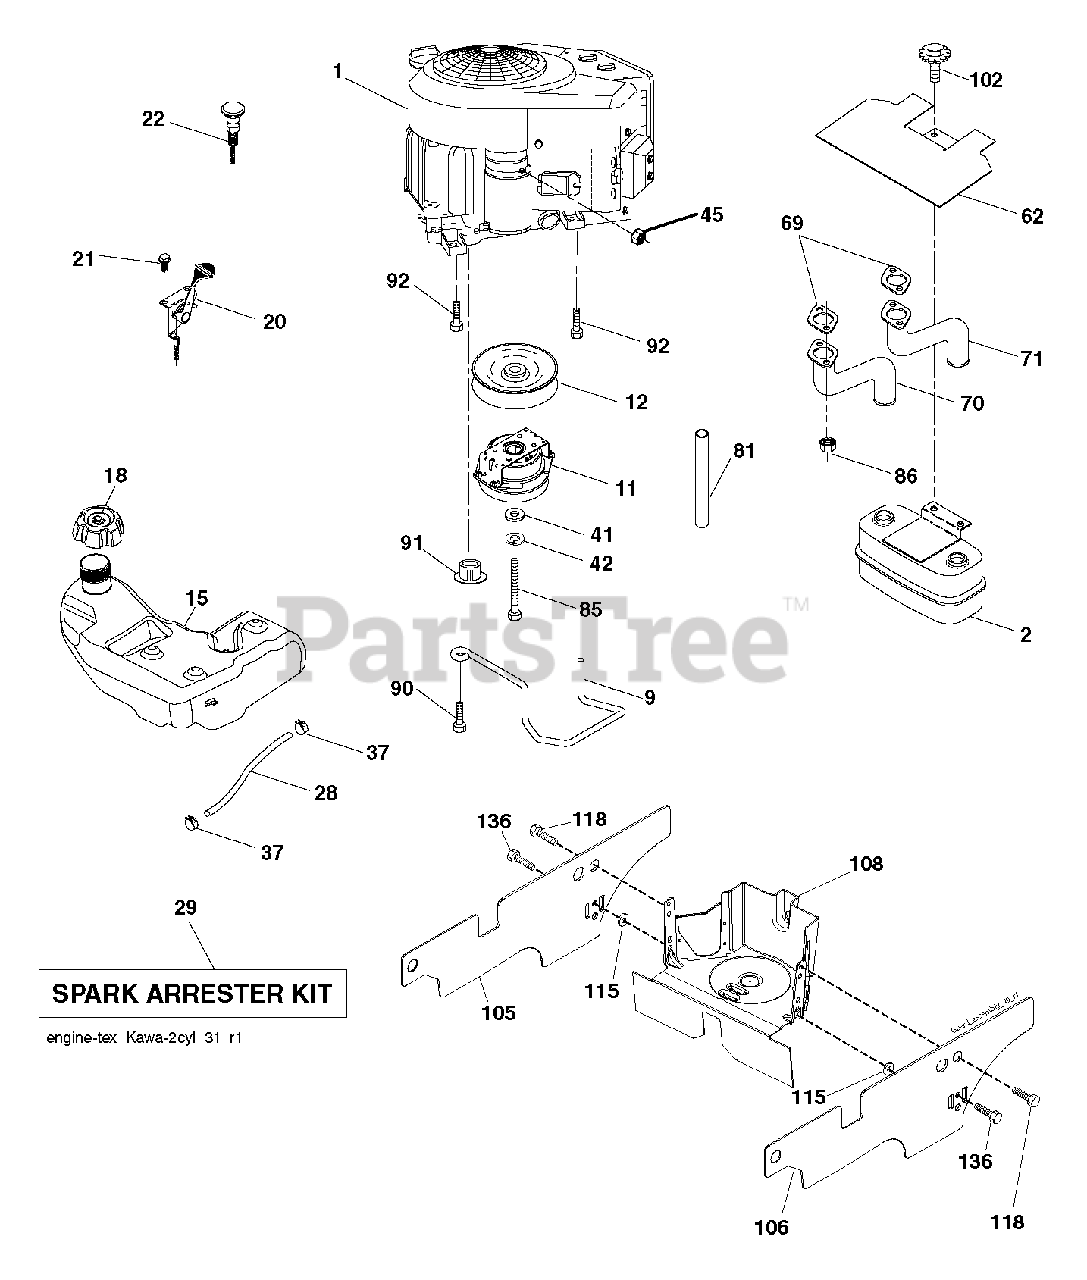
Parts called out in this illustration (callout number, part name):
2	MUFFLER.ASM.TWN.EXTNDED.DFLCTR
9	KEEPER BELT ENGINE
11	CLUTCH.OGURA.5.0PD.GT1.5A-EH07
12	PULLEY.ENGINE.TUFFTORQ
15	TANK.FUEL.4GAL
18	CAP.FL.R.3'N/CARB.H.CROWN.498
20	CONTROL.THROTTLE.COBRA.BLACK
21	SCREW.#10 X 0.750.BOS
22	CONTROL, CHOKE
28	REPL BY 532 00 85-43
29	KIT.SPARK ARRESTOR 794945 B&S
37	HOSE CLAMP
42	LOCKWASHER
45	NUT
62	SHIELD.HEAT.MUFFLER
70	TUBE.EXHAUST.LH.FR961/FR730
71	TUBE.EXHAUST.RH.FR961/FR730
81	TUBE, DRAIN OIL ASM.
85	BOLT HEX 7/16-20 X 3.75 GR. 5
86	NUT.HEX.FLANGE.TOPLOCK
90	SCREW 3/8-16X1
91	BUSHING.1.375OD
92	SCREW 3/8-16X1
102	SCREW
105	SHIELD.SIDE.RH.3842"TEX FRENCH
106	SHIELD.SIDE.RH.46"FRENCH.TEX
108	COVER
115	PALNUT 1/4
118	SCREW, 5/16-18 X 1/2
136	SCREW.1/4-20X5/8
